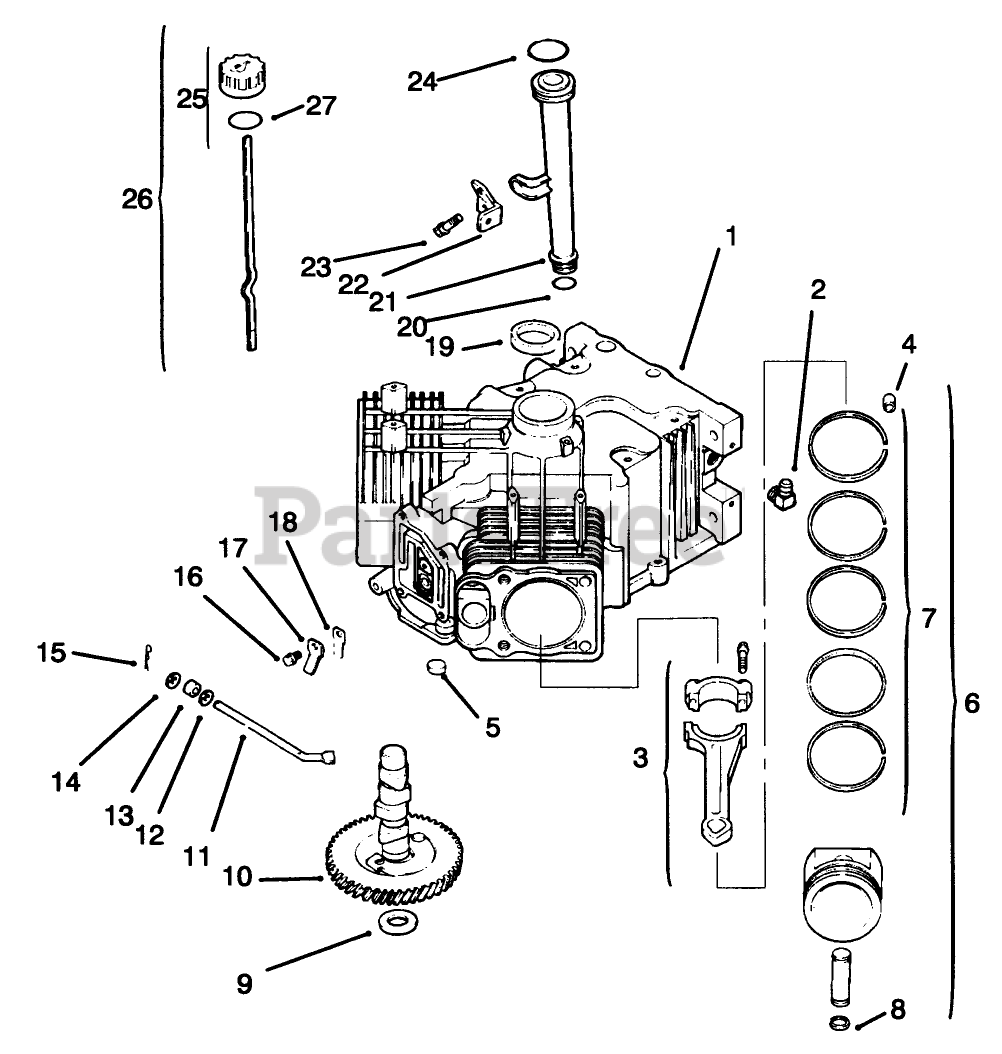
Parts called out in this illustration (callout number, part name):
1	Short Block (Only On: 72103)
2	Connector
3	Connecting Rod STD
3	Connecting Rod .25
4	Pin-Dowel
6	Piston w/Ring Set (Std.) (Incl. Ref. # 4-6)
6	Piston w/Ring Set (.25)
6	Piston w/Ring Set (.50)
7	Set-Ring (Std)
7	Ring Set (.25)
7	Ring Set (.50)
8	Retainer-Piston Pin
9	Shim-Camshaft
10	Camshaft
11	Shaft-Governor Cross
12	Washer-Flat
13	Seal
14	Washer
15	Pin-Hitch
17	Retainer-Reed (Only On: 72103)
18	Beed-Breather
19	Seal-Oil
20	O-Ring-Lower Fill Tube (Only On: 72042, 72063, 72062, 72043)
21	Tube-Oil Fill (Only On: 72103, 72083)
22	Bracket-Oil Fill Tube (Only On: 72103)
23	Screw M5x0.8x16 (Only On: 72042, 72063, 72062, 72043)
24	O Ring-Upper Fill Tube (Only On: 72103)
25	Dipstick INC 26-27 (Only On: 72103, 72083)
26	Kit-Oil Fill Cap (Incl. Ref. #7)
27	ORing
